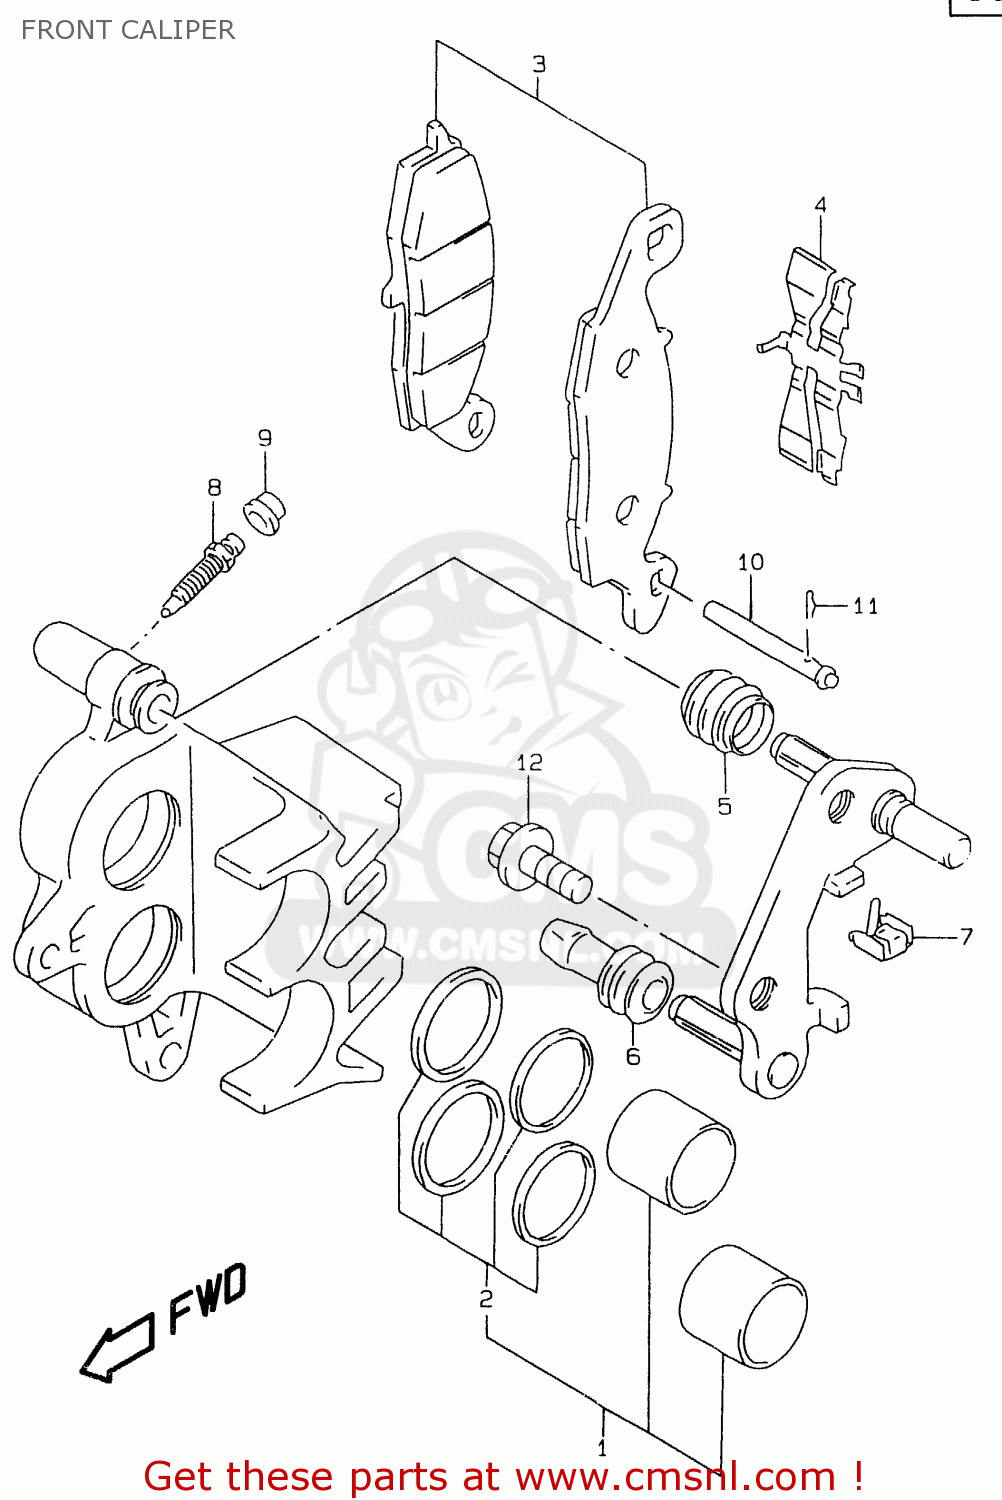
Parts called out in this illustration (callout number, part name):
1	PISTON SET
2	SEAL SET,PISTON
3	PAD SET (NAS)
4	SPRING,PAD,R
5	BOOT,AXLE
6	INSULATOR,AXLE
7	GUIDE,PAD
8	BLEEDER
9	CAP,BLEEDER PLUG
10	PIN,PAD
11	CLIP,PAD PIN
12	BOLT
